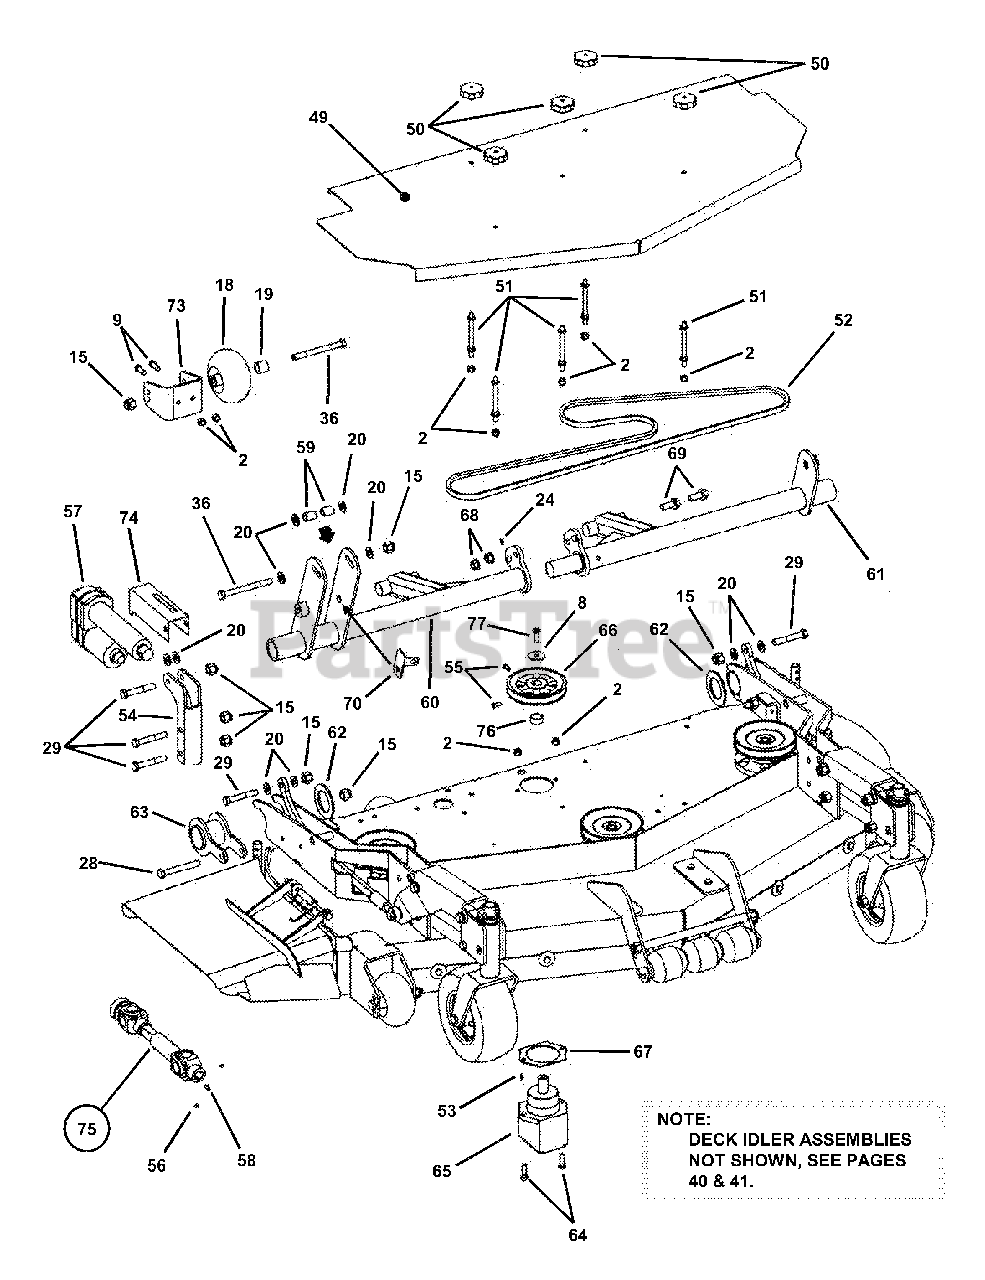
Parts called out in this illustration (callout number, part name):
2	NUT, 3/8-16 HEX NYLON LOCK
8	WASHER, 13/32 x 1-1/2" Flat
9	BOLT, 3/8-16 X 1" GD5 CZ
15	NUT, 1/2-13 Hex Nyloc
18	WHEEL, Gage
19	SPACER, Gage Wheel
20	WASHER, 1/2" Flat
24	FITTING, Lube 1/4-28 Straight
28	BOLT, 1/2-13 x 3-3/4" Hex Head Cap, Grade 5
29	BOLT, 1/2-13 X 3" GD5 CZ
36	BOLT, 1/2-13 X 5 GD5 YZ
49	STIFFENER, 61" Deck, Left Hand
49	COVER, 61" Deck
50	STIFFENER, 61" Deck, Right Hand
50	KNOB, 5/16-18 Thread
51	STANDOFF, 3-1/2"
52	V-BELT, 61" (134.5") HB
53	KEY, #6 x 5/8" Woodruff
54	MOUNT, Motor (Front)
55	SCREW, 5/16-18 x 5/8" Square Head Set w/locking patch
56	SCREW, 3/8-16 x 3/8" Hex Recess Set
57	SCREWJACK, Warner Electric 1000 lbs.
58	KEY, #9 Woodruff
59	SPACER, Motor, Rear
60	MAIN LINK (Weldment)
61	MAIN LINK (Weldment) Left Hand
62	SPACER, Tube
63	HOLDER, Pivot (Weldment)
64	BOLT, 3/8-16 X 1-1/4" GD5 CZ
65	GEARBOX, Right Angle (Peerless P/N 1000-52)
66	PULLEY, Cast 5.25" Outside Diameter
67	SHIM, Gearbox
68	NUT, 1/2-13 Hex Flange Lock, Grade 5
69	BOLT, 1/2-13 x 1-1/4" Hex Flange Lock, Grade 5
70	BRACKET, Strain Relief
73	BRACKET, Gage Wheel
74	INDICATOR, Height-of-Cut
75	ASSEMBLY, Telescoping Drive Shaft
76	SPACER
77	BOLT, 3/8-24 X 1" GD8 YZ
